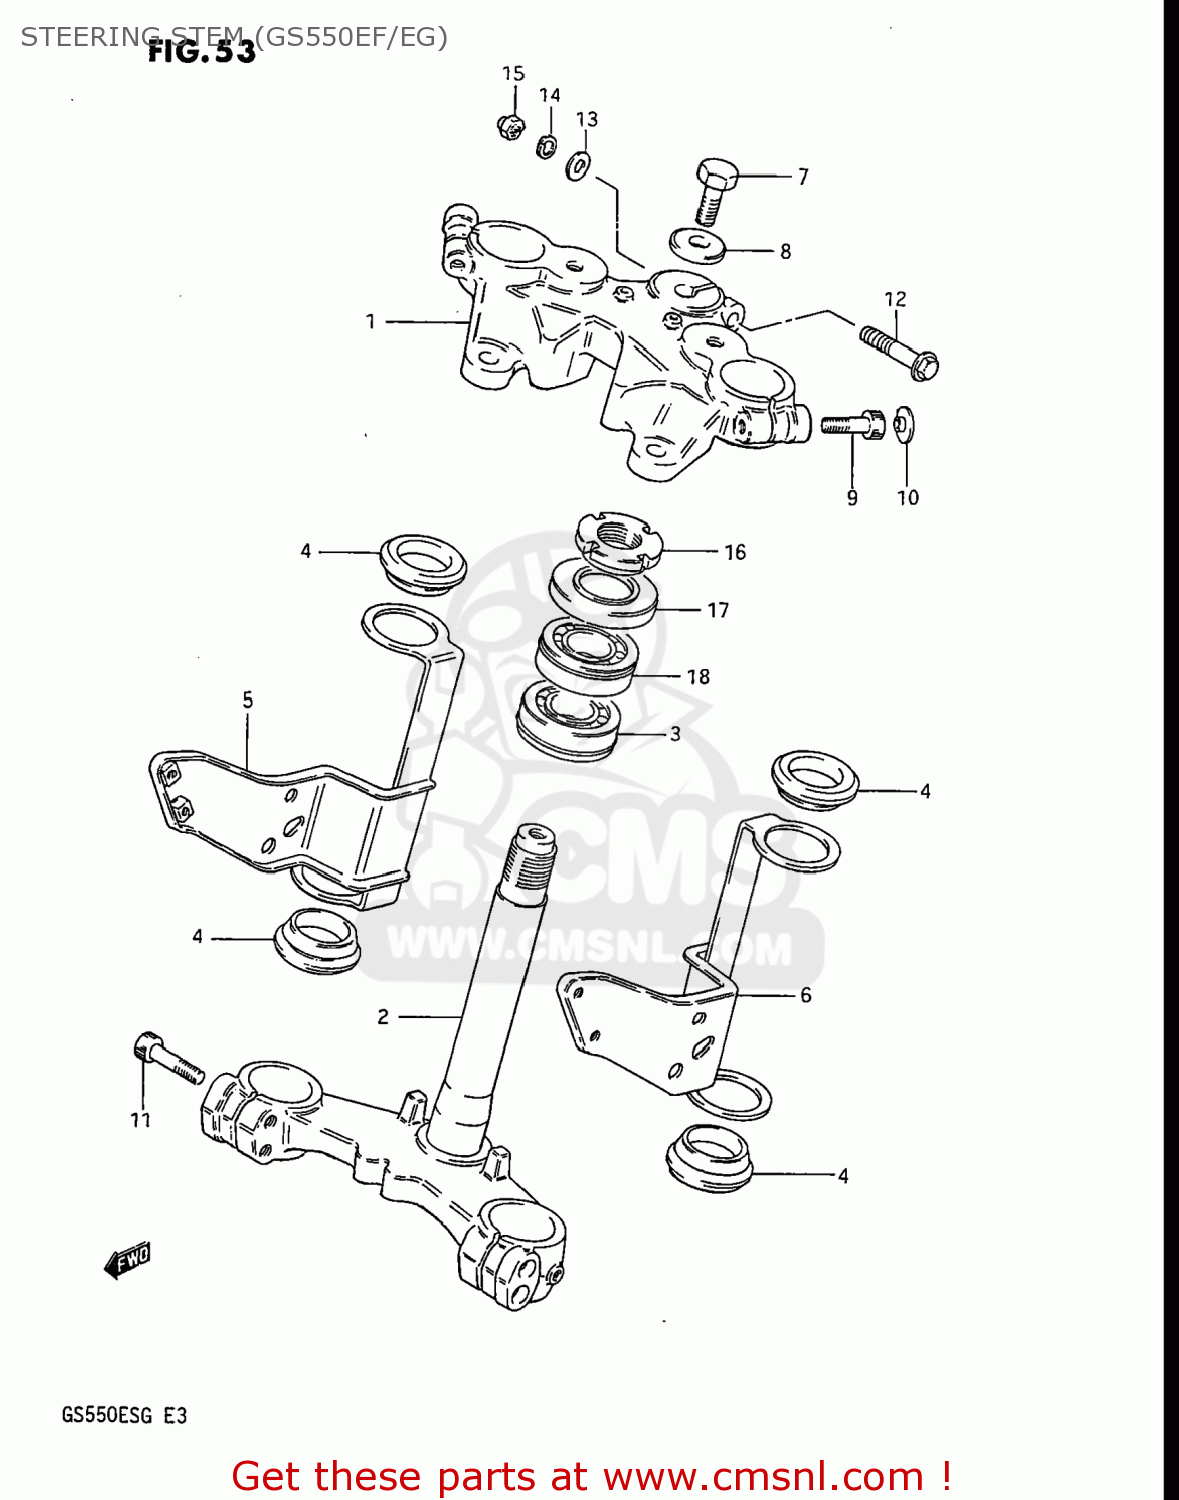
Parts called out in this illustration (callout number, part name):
1	HEAD,STEERING STEM
2	STEM,STEERING
3	BEARING
4	CUSHION,HEADLAMP BRACKET
5	BRACKET,HEADLAMP,RIGHT
6	BRACKET,HEADLAMP,LEFT
7	NUT,STEM HEAD
8	SUZUKI
9	BOLT,FORK INNER TUBE FITTING
10	CAP(OD:20)
11	BOLT, REAR (8X30)
12	BOLT, UPPER
13	WASHER
14	WASHER,LOCK,8.
15	NUT,M8X1.25X12
16	NUT,STEERING STEM
17	DUST SEAL,STEERING UPR
18	TAPER,ROLLER BEARING
